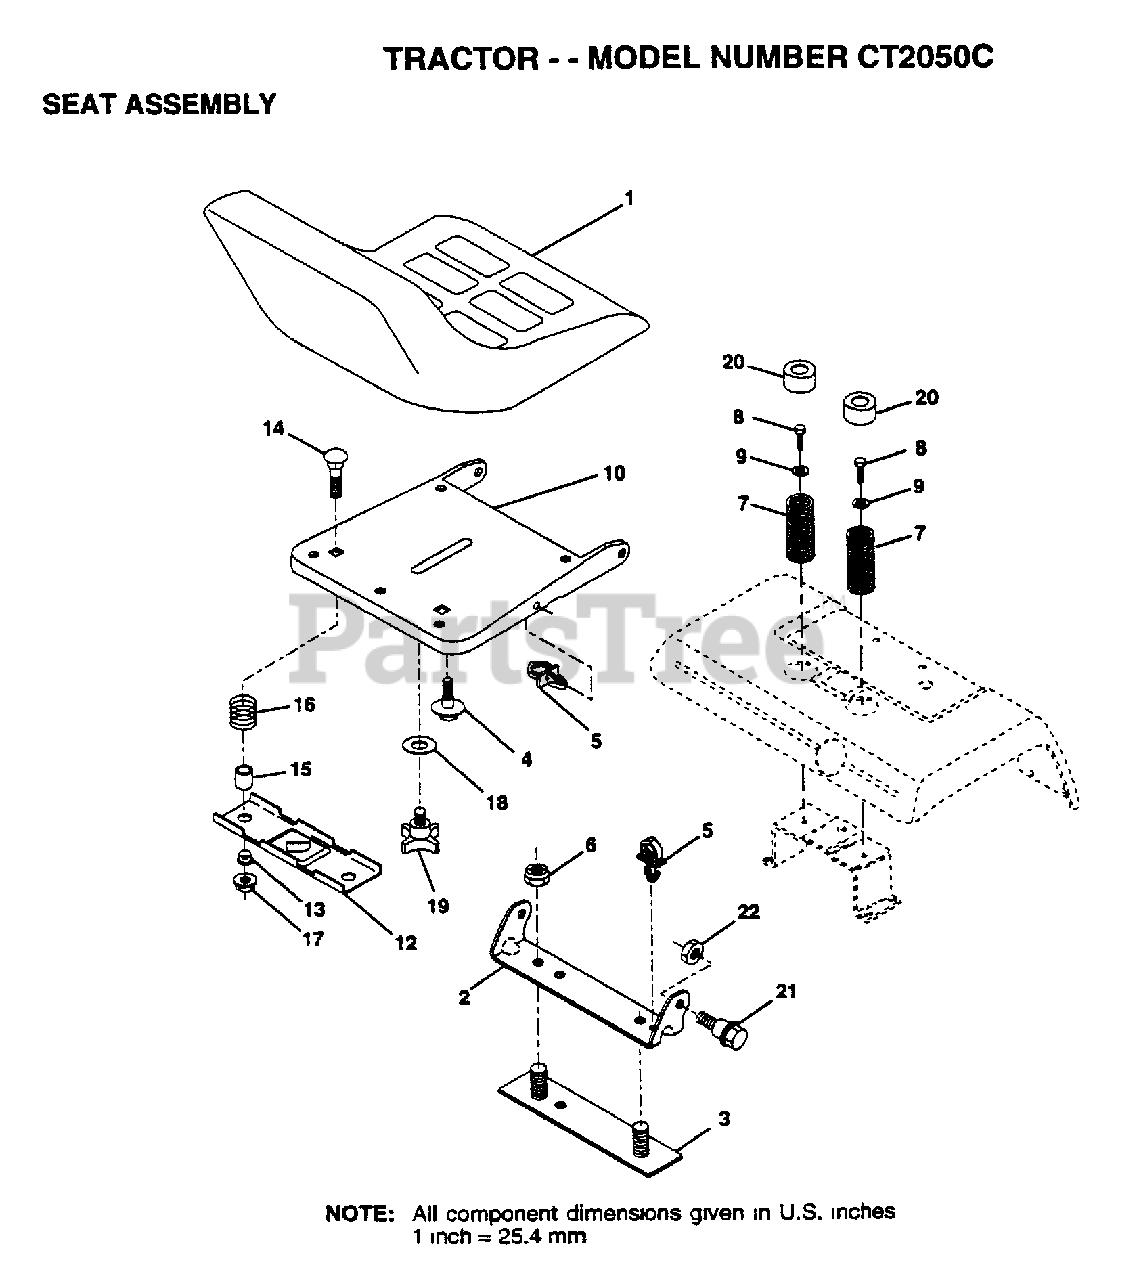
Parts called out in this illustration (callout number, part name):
2	BRACKET PVT SEAT
3	STRAP ASM FENDER
4	"BOLT,SHOULDER"
5	CLIP.PUSH-IN.HING
7	SPRING COMPRESSIO
8	SCREW LT
9	WASHER
12	BRKT SWITCH
13	BUSHING
15	SPACER SPLIT
16	SPRING COMPRESSED
18	WASHER
19	"KNOB 1/2"" YT"
20	CAP SPRING
21	BOLT.SHLD.5/16-18
